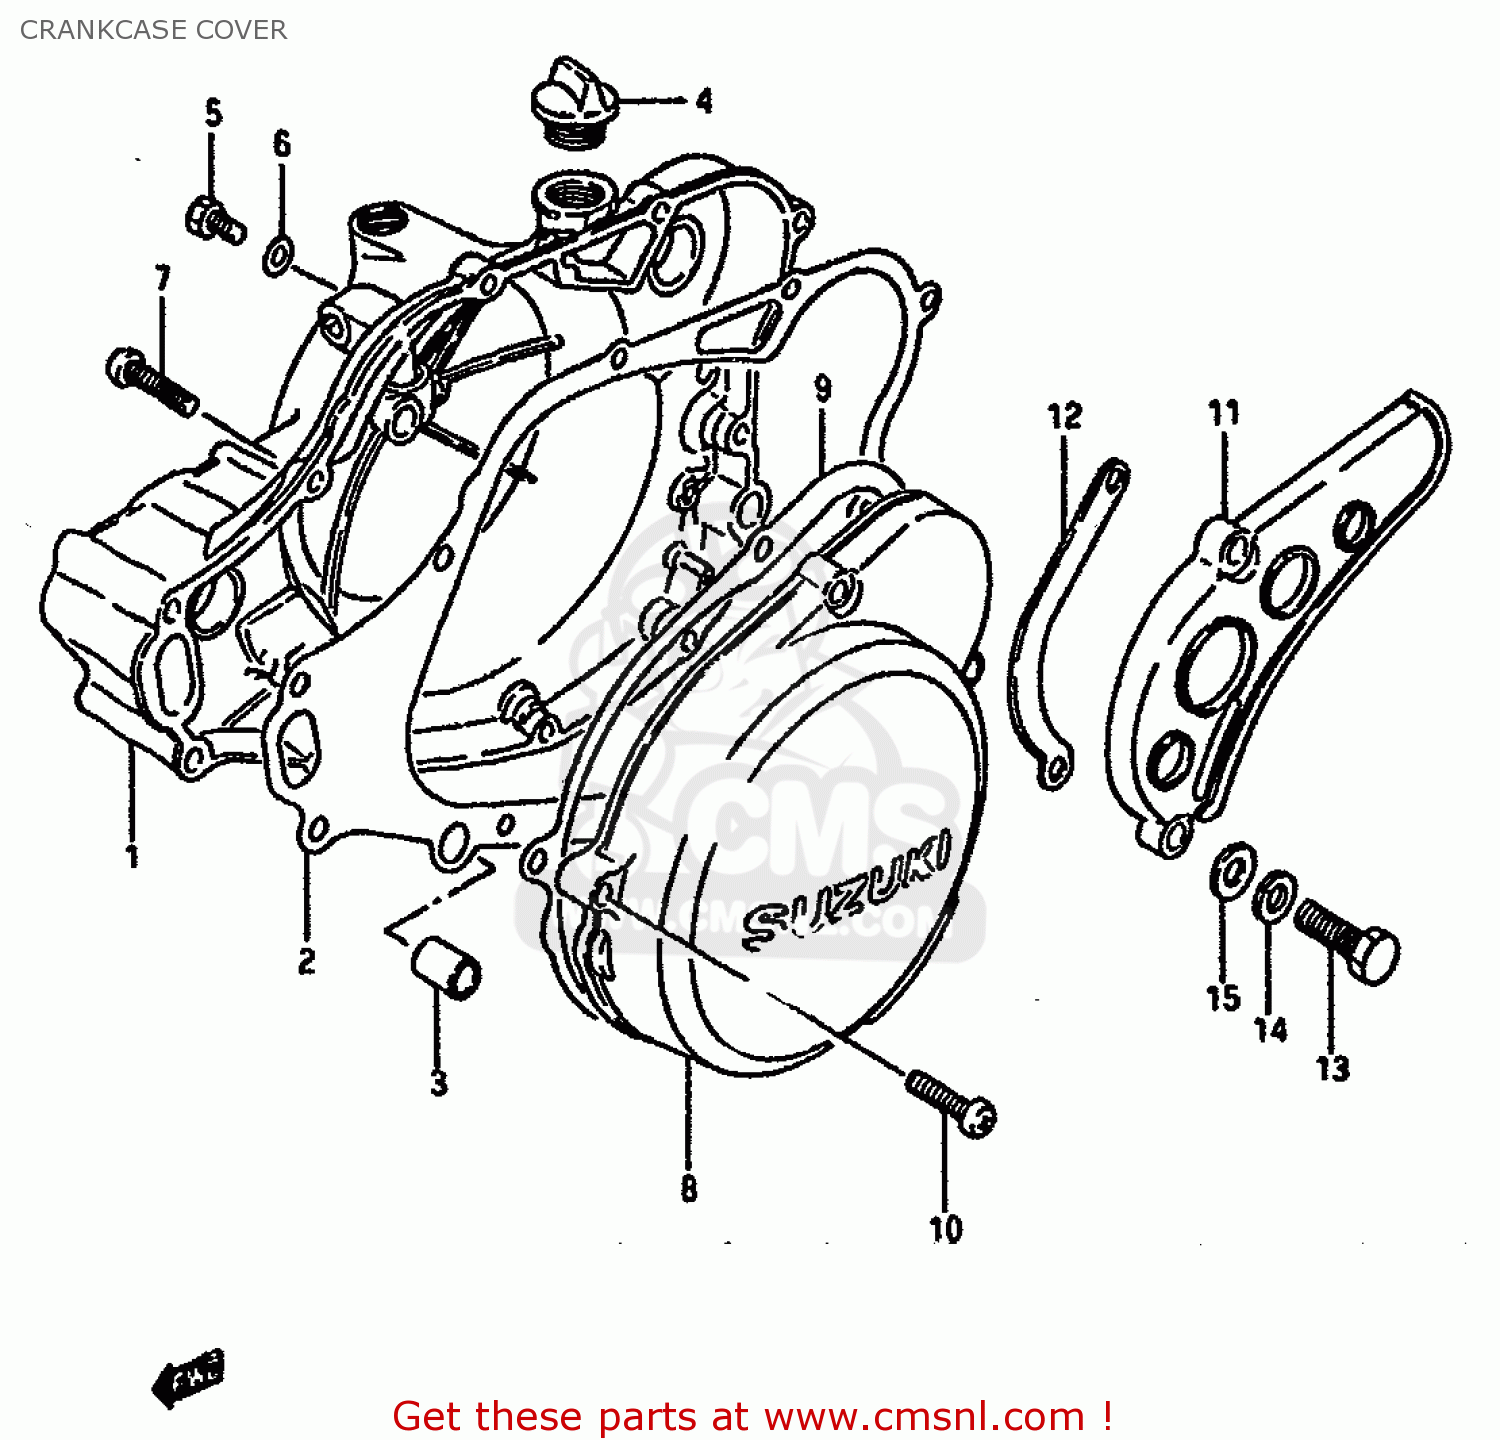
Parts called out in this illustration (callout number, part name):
1	COVER,CLUTCH
2	GASKET,CLUTCH COVER (MCA)
3	PIN
4	PLUG SET
5	SCREW(6X10)
6	GASKET(6.2X11X1) (NAS)
7	SCREW
8	COVER,MAGNETO
9	GASKET,MAGNETO COVER (NAS)
10	SCREW
11	COVER,SPROCKET
12	PLATE,FR CHAIN GUIDE
13	BOLT
14	WASHER,LOCK,8.
15	WASHER
